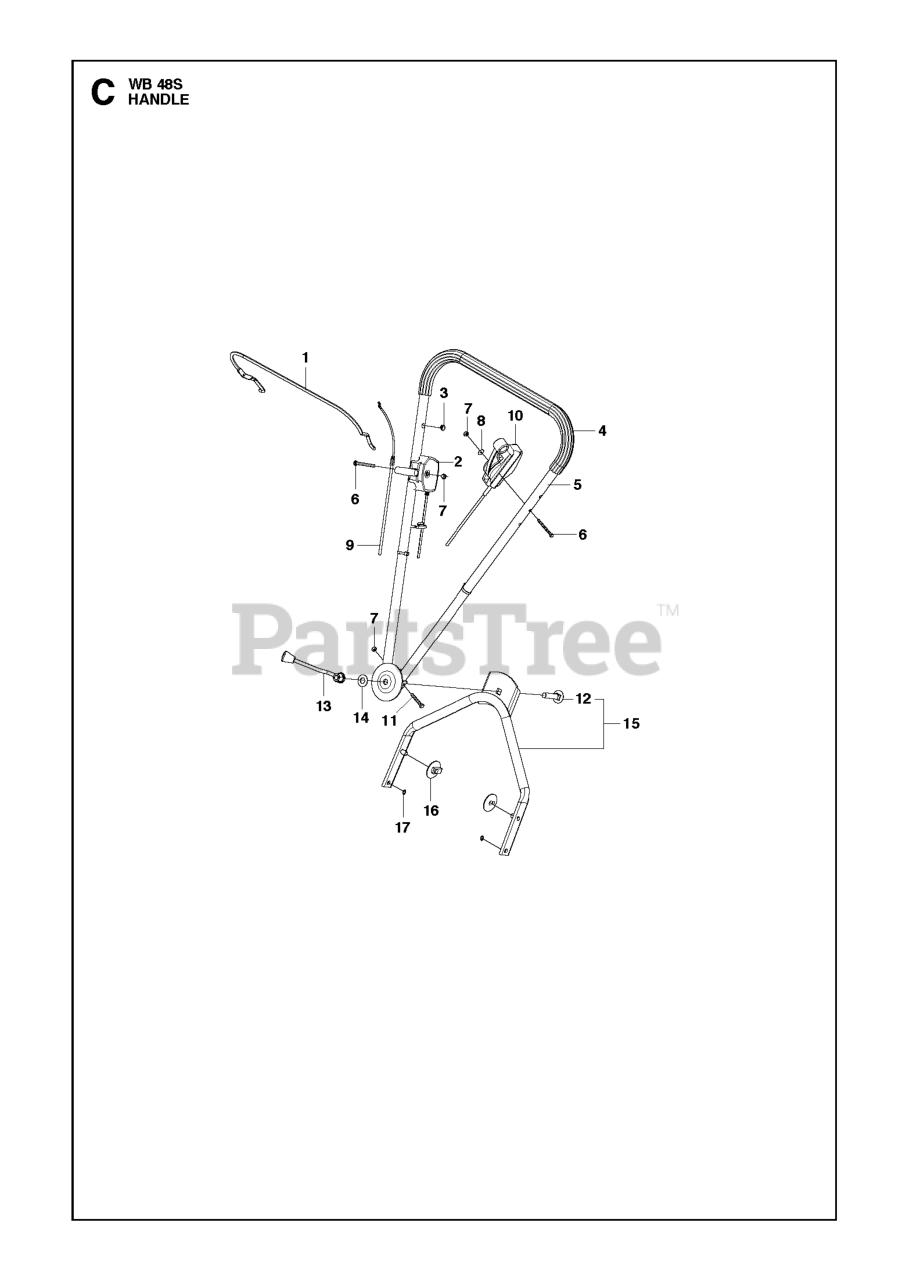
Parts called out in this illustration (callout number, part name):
6	SCREW M6X55
7	NUT FLANGE - M6
11	Hex Head Capscrew, M6 X 1.00 X 40MM
17	RETAINING RING SGA 10
